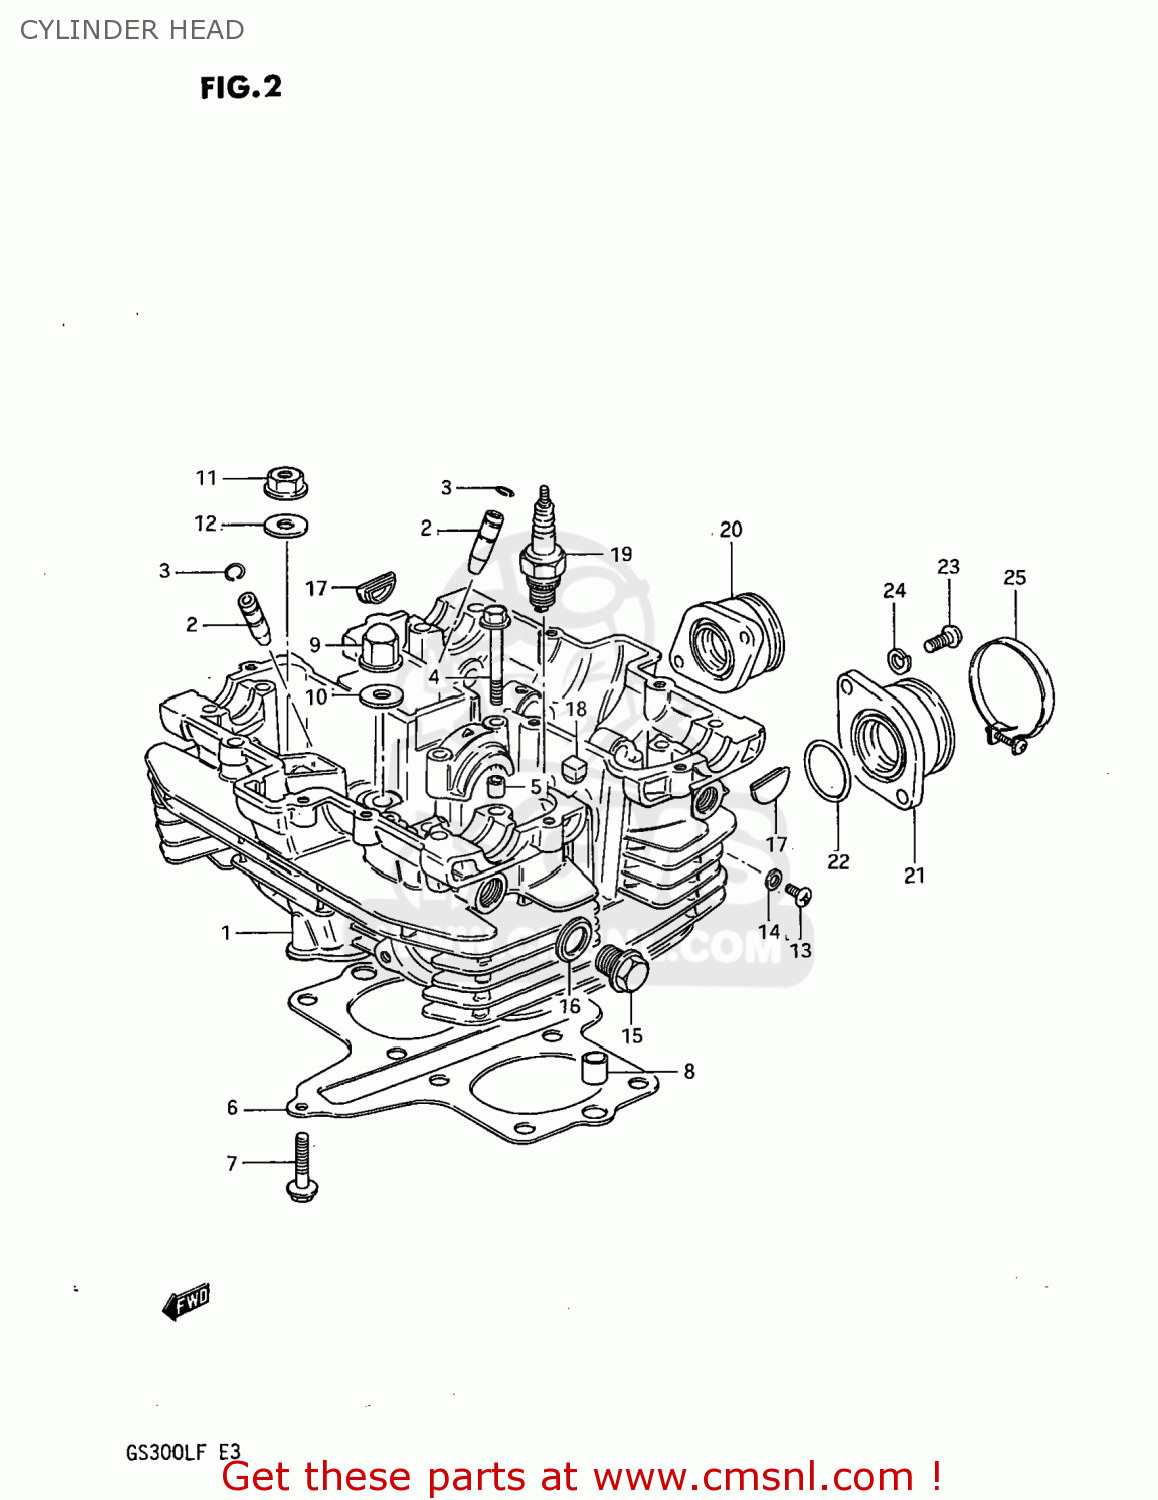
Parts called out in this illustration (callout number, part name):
1	HEAD ASSEMBLY,CYLINDER
2	GUIDE,INTAKE VALVE
3	RING,SNAP
4	BOLT(6X39)
5	PIN(6.2X8X11)
6	GASKET,CYLINDER HEAD (NAS)
7	BOLT 6X30
8	PIN
9	NUT
10	GASKET (NAS)
11	NUT
12	WASHER(8.5X19X2.3)
13	SCREW
14	GASKET(5.3X9.3X1.2) (NAS)
15	PLUG (14X12)
16	GASKET(14X19.2X2) (NAS)
17	PLUG
18	PAD,CYLINDER HEAD
19	SPARK PLUG D9EA
20	PIPE,INTAKE,R
21	PIPE,INTAKE,L
22	O-RING (D:2.4 ID:29.7)
23	SCREW
24	LOCK WASHER
25	CLAMP
